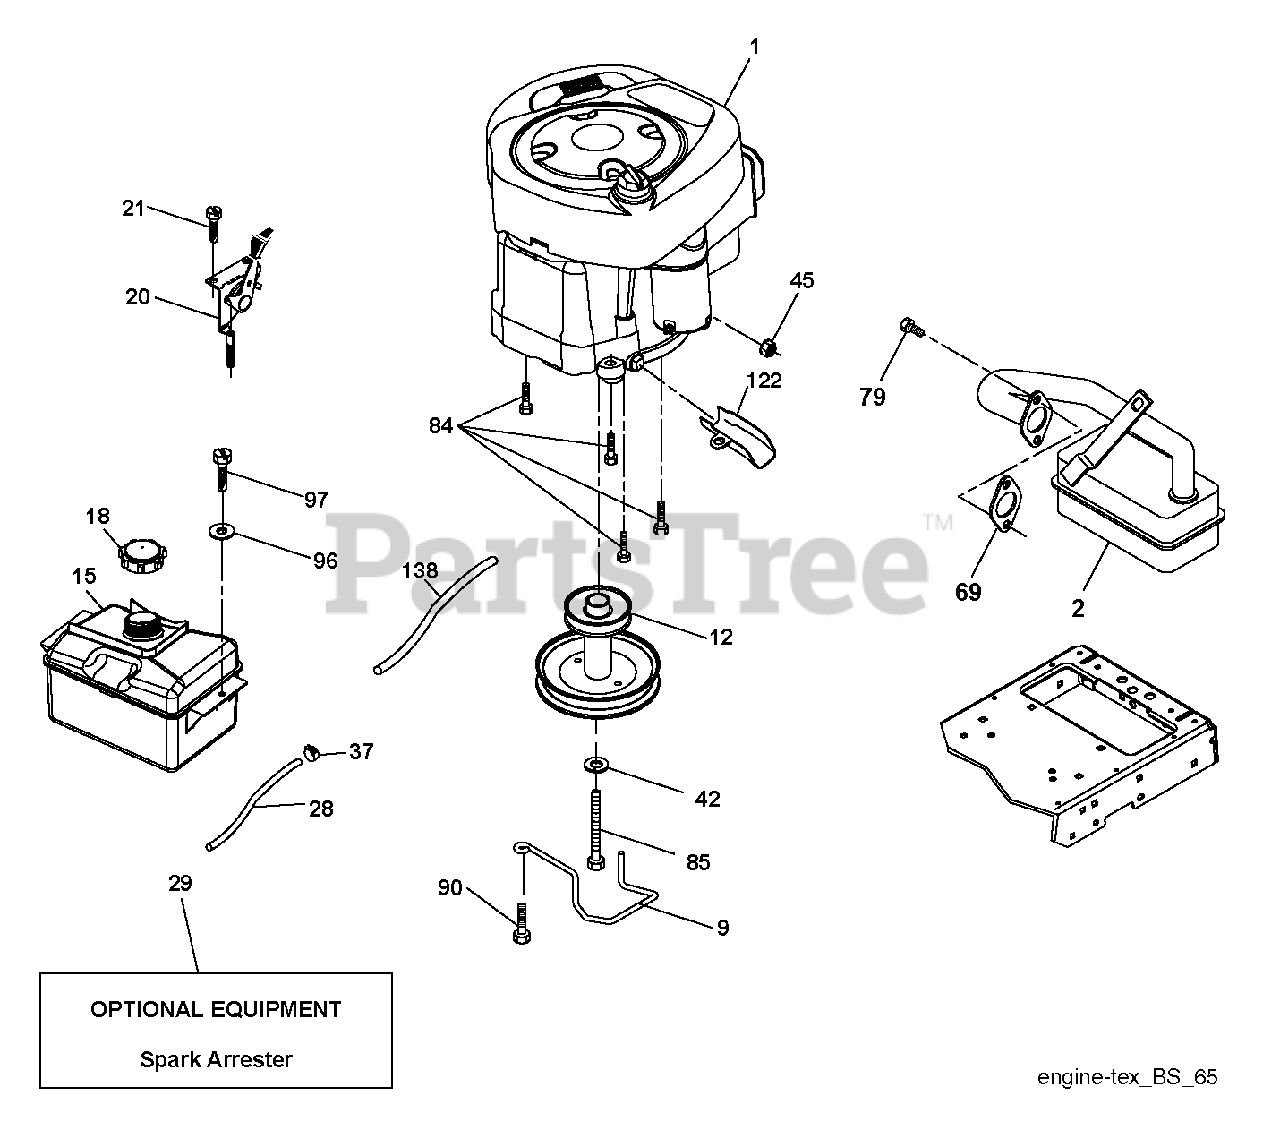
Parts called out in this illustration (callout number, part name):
2	MUFFLER.LT.BRIGGS.14HP.IC/OHV
9	KEEPER.BELT.ENGINE.3.25
12	PULLEY.ENGINE.5.0.PD
15	TANK.ASM.1.5GAL.FRT.W/CAP.EPA
18	CAP ASM.FUEL.2.25"FR.
21	SCREW.#10 X 0.750.BOS (2 2)
28	LINE.FUEL.20"FRONT.EMI
29	SPARK ARRESTOR KIT
37	HOSE CLAMP
42	LOCKWASHER
45	NUT
79	SCREW.SOCKET HD.5/16-1
84	SCREW.3/8-16
85	BOLT HEX 7/16-20X4-1/4"
90	SCREW 3/8-16X1
97	SCREW HEXWSHR 1/4-20X3/4
122	EXTENSION DRAIN OIL
138	RP PURGE LINE
